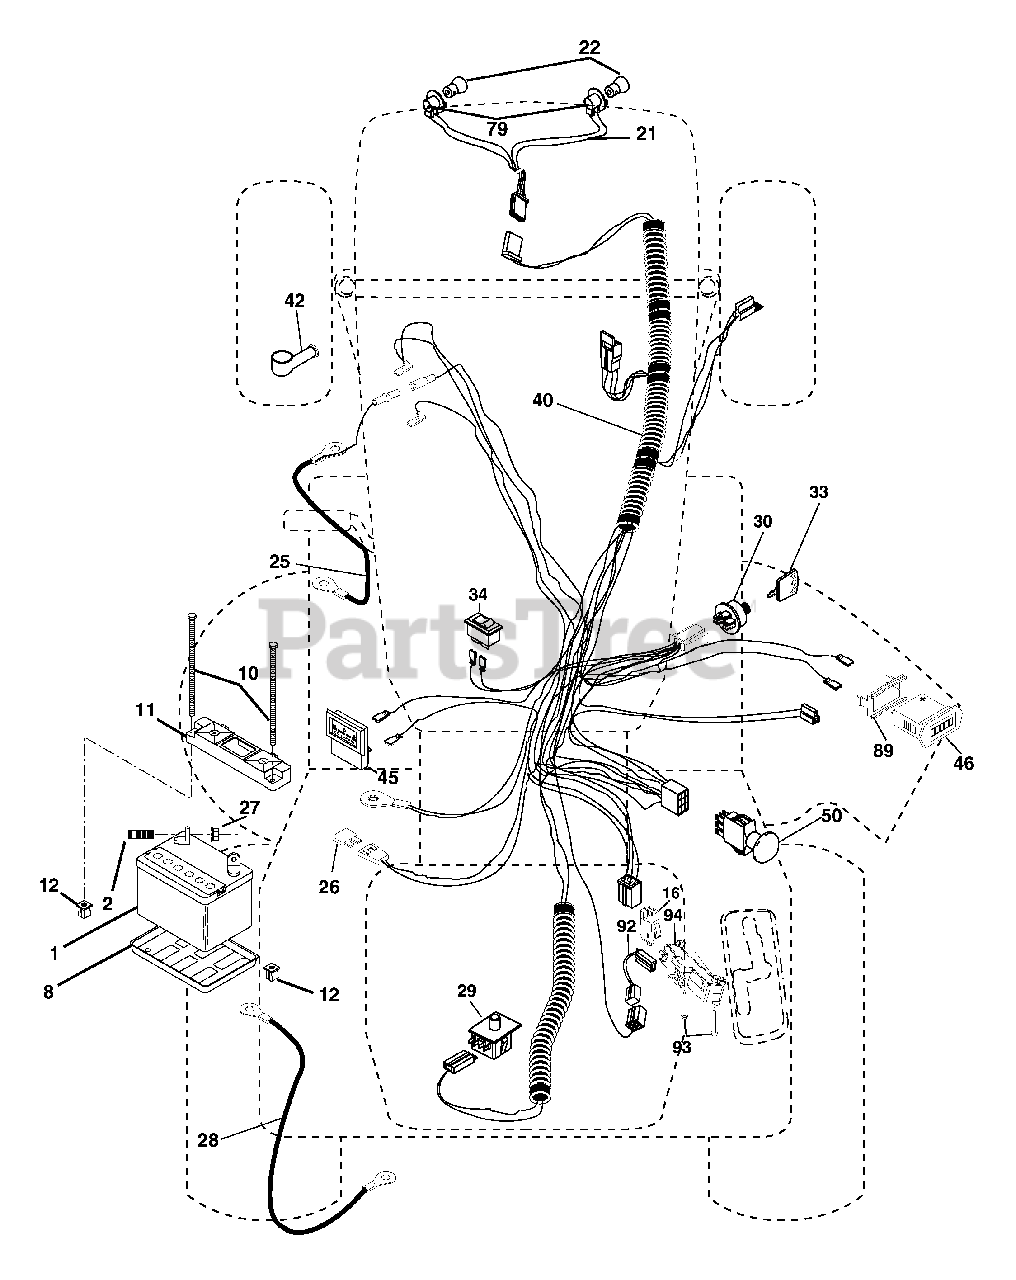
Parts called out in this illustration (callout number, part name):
1	Battery
2	Bolt Hex Head 1/4-20 x 3/4
8	Tray, Battery
10	Bolt Btr Frt 1/4-20 x 7.5 zinc
11	Holdown Battery Front Mount
12	Nut Push Nylon 1/4"
16	Switch Interlock Push-In
21	Harness Headlight w/Bulbs
22	Bulb Light
25	Cable, Battery
26	Fuse
27	Nut Keps Hex 1/4-20 unc
28	Cable, Ground
29	Switch, Seat
30	Switch, Ign
33	Key
34	Switch Light/Reset
40	Harness, Ignition
42	Cover, Terminal
45	Ammeter
46	Hourmeter Snap-In
50	Switch, PTO
79	Socket, Light Bulb
89	Bracket Snap-In
92	Harness Pigtail Reverse Switch
93	Screw Plastite 10-14 x 2.0
94	Module Reverse ROS
